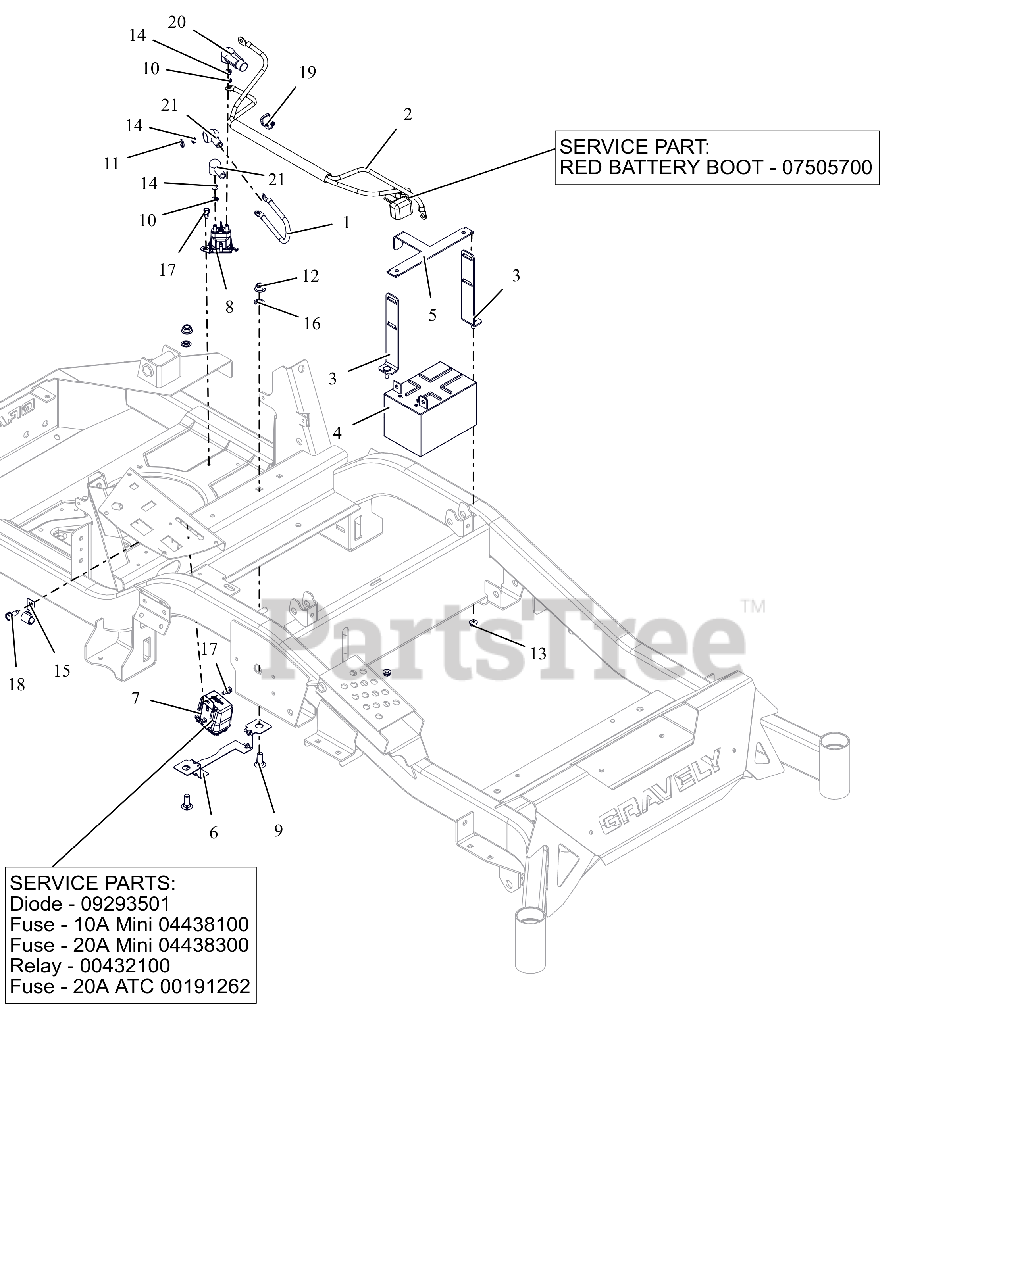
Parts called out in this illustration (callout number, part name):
1	CABLE, POS W/(2)1/4 RING 9.0LG
2	HARNESS, BATTERY HD
2	INSULATOR
3	WMT,BATTERY MOUNT HOLD DOWN
4	BATTERY, 12V 12A-190CCA
5	BRKT, BATTERY TIE DOWN
6	GUARD, ELECTRICAL HARNESS
7	HARNESS, WIRE
7	DIODE, CONNECTOR SHELL
7	FUSE,10 AMP MINI-ATC
7	FUSE,20 AMP MINI ATC
7	RELAY,SEALED W/DIODE
7	FUSE, 20 AMP BLADE S/O
8	SOLENOID, STARTER (SEALED)
9	BLT, RHSN .38-16X1.00 G5 ZCC
10	WSHR,LK-EXT.262X.502X.026 ZCC
11	WSHR,LK-REG .312X.078 ZCC
12	NUT,NYL-FLG .38-16 GF ZCC
13	NUT-LK-TOP-FLG .250-20 GF ZCC
14	NUT-STD M6-1.0 ZCC
16	NUT-PUSH .38 DIA. PAL ZINC
17	SCR-TAP .25-20X.50 HWH ZCC
18	SCR,TAP .312-18X.75 HWH TR ZCC
19	CABLE TIE W/ TREE (.25 HOLE)
20	BOOT, .65ID POS
21	BOOT, EYELET TERMINAL
